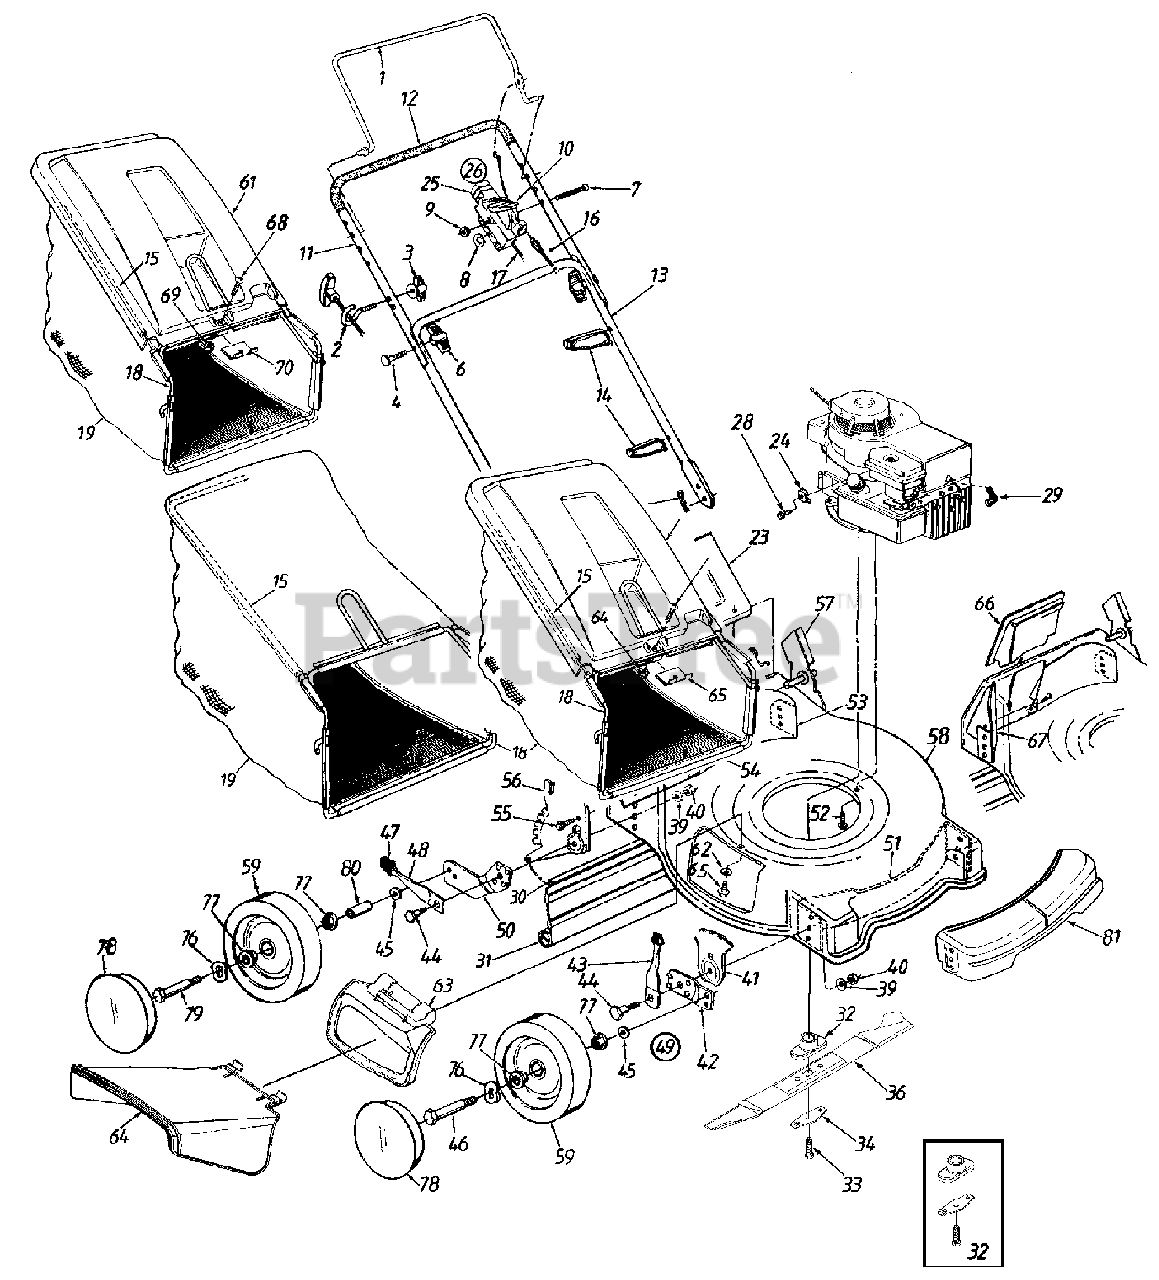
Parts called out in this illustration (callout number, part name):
2	Rope Guide
3	Handle Knob 1/4-20 Thd.
4	Curved Hd. Bolt 5/16-18 x 2" Lg.
6	Hand Knob
7	Oval C-Sunk Mach. Scr.
8	Spr. Wash. .66" I.D.
9	Hex L-Nut 1/4-20 Thd.
10	Throttle Lever
14	Cable Tie
16	Control Cable - 36"
17	Throttle Control Wire-55"
25	Throttle Body
26	Throttle Box Comp.
28	Hex Wash. Hd. Scr. #10-32:.62" Lg.
29	Spark Plug Boot
30	Wire Rod
31	Rear Flap
32	Blade Adapter Kit
33	Hex Bolt 3/8-24 x 1.5" Lg.
34	Blade Bell Support
36	21" Mulching Blade
39	Bell-Wash. .39" I.D. x 1.38"
40	Hex Nut 3/8-16 Thd.
41	Height Adj. Plate
43	Spring Lever Ass'y. w/Knob
44	Shld. Bolt .5" Dia. x .357"
45	Bell-Wash. .38" I.D. x .88" O.D.
46	Front Axle Bolt
47	Spring Lever Knob
48	Spring Lever
49	Height Adj. Ass'y. Comp. - R.H.
50	Pivot Bar R.H.
54	Torx Mach AB-Tap Scr. 1/4 x.62" L.
55	Hex Ind Wash. Scr. 1/4-14:.625
59	Wheel Assy Comp. Wheels with Bearings Grey Link Tread
59	Wheel Assy Comp. Wheels with Bearings Beige Link Tread
59	Wheel Assy Comp. Wheels with Bearings Yellow Link Tread
61	Hard Top Cover w/o Icon
62	Bell-Washer 1/4" I.D.
63	Hinged Mulching Plug
64	Chute Deflector
65	Hex Hd Self-Tp Scr. 1/4-20 x .5" L.
66	Mulching Baffle Plug
68	Pan Hd. Mach. Scr. 1/4-20:.5" Lg.
69	Hx. Nylon L-Nut - 1/4-20 Thread
76	Wave Washer
77	Ball Bearings
78	Hub Cap - Rad. Spoke - Grey
79	Rear Axle Bolt
80	Spacer
81	Cover - Front End - Yellow
